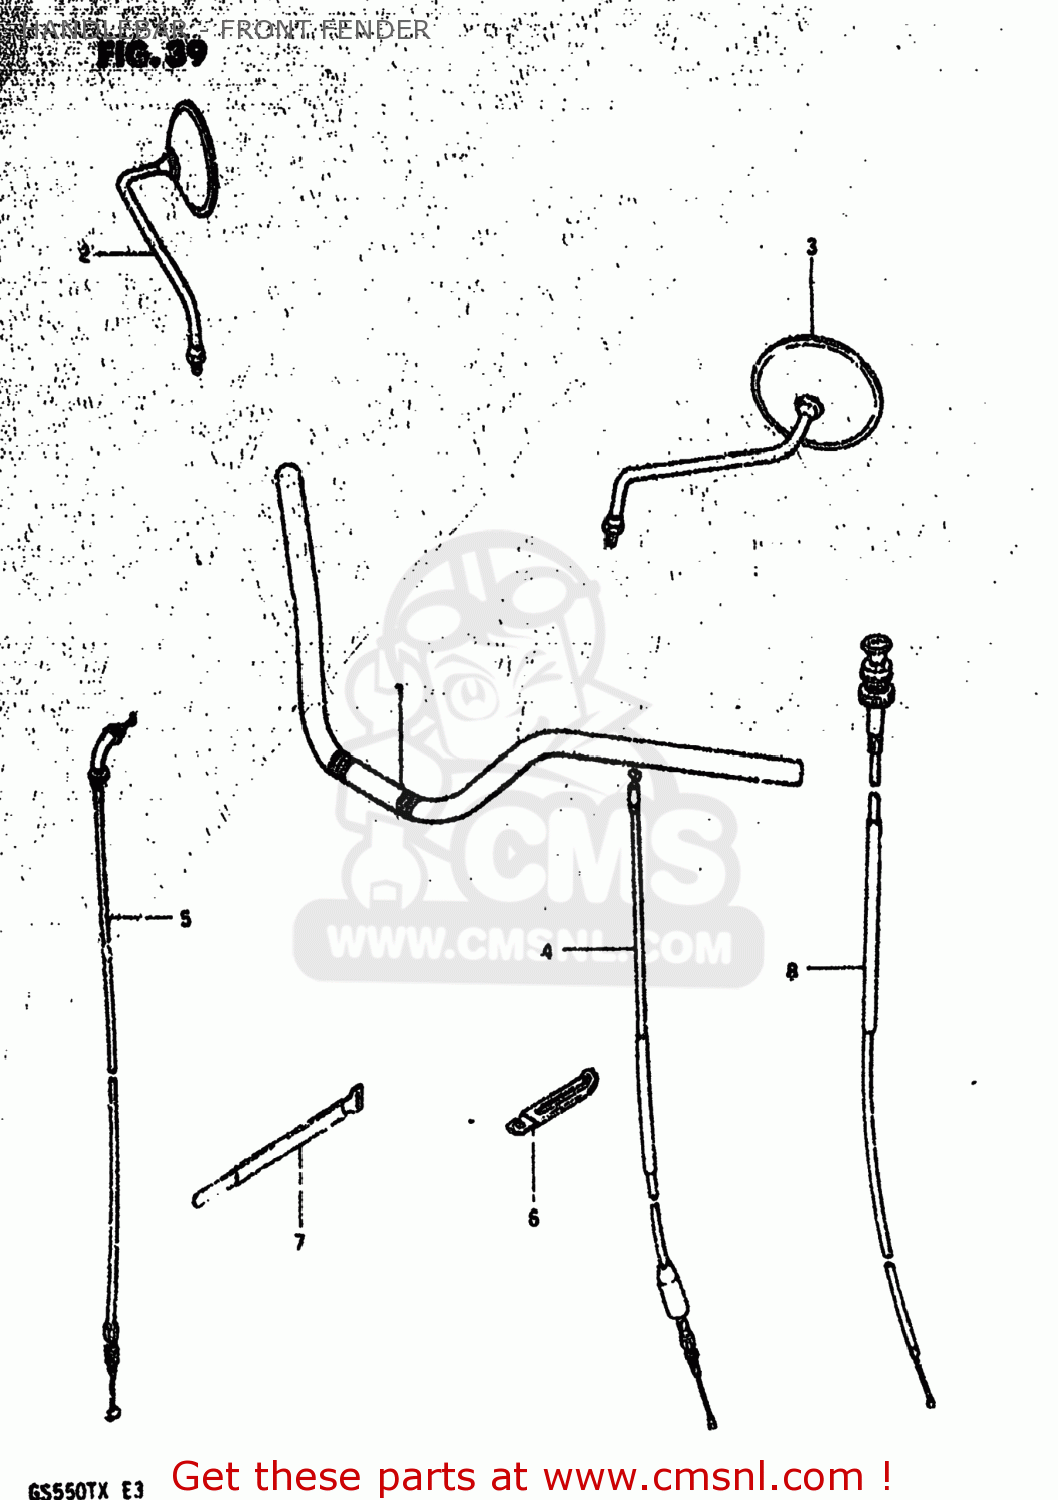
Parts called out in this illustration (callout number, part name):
1	HANDLEBAR
2	MIRROR ASSEMBLY,REAR VIEW
3	MIRROR ASSEMBLY,REAR VIEW
4	CABLE ASSY,CLUTCH
5	CABLE ASSEMBLY,THROTTLE
6	CLAMP
7	CLAMP
8	CABLE ASSEMBLY,STARTER
